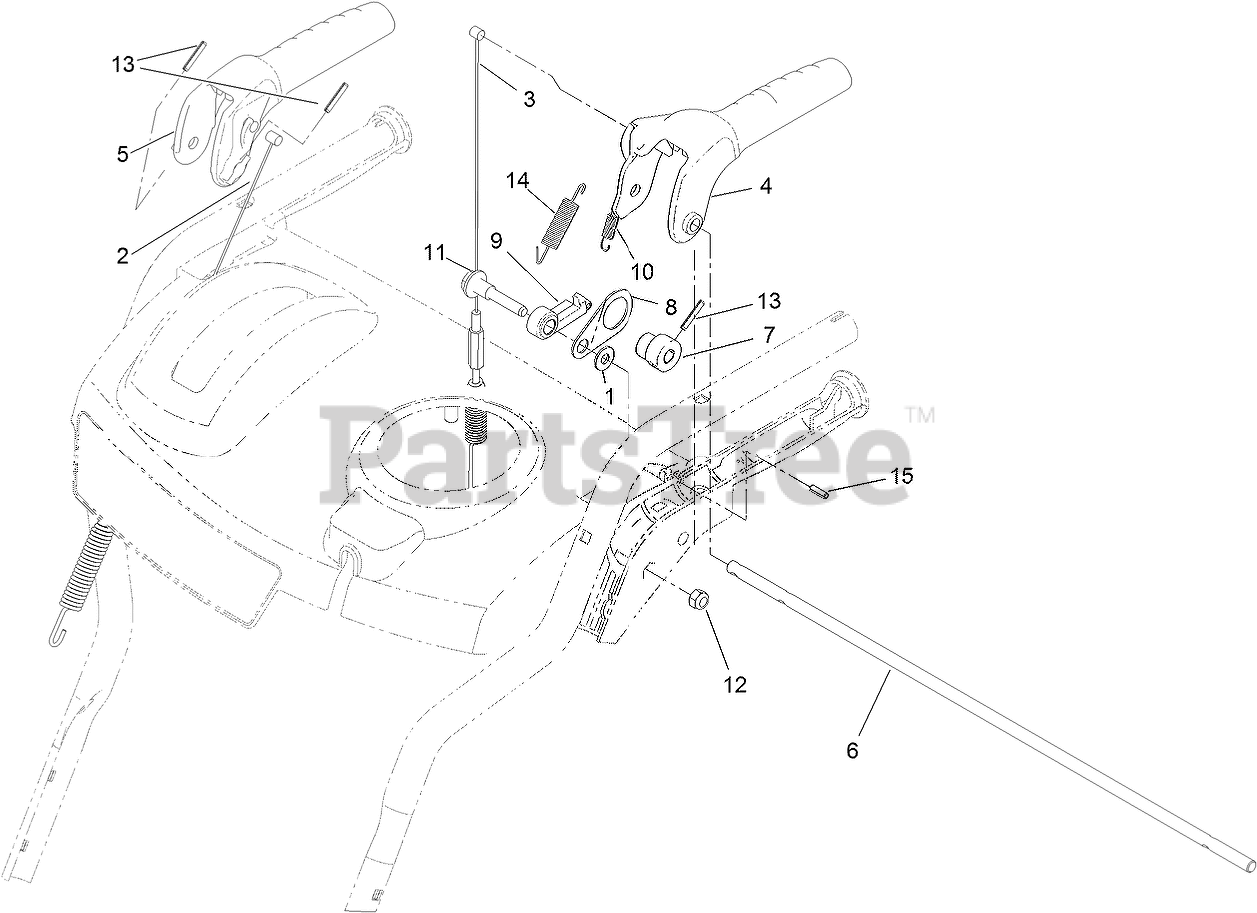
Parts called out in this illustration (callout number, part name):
1	WASHER-FLAT
2	CABLE-AUGER
3	CABLE-TRACTION
4	HANDLE-CONTROL, TRACTION
5	HANDLE-CONTROL, AUGER
6	ROD-LOCKOUT
7	CAM-LOCKOUT
8	LINK-LOCKOUT
9	LATCH-LOCKOUT
10	SPRING-LOCKOUT, HANDLE
11	SCREW-SHOULDER
12	NUT-HEX
13	PIN-SPRING
14	SPRING-RETURN, LEVER
15	PIN-ROLL, SLOTTED
